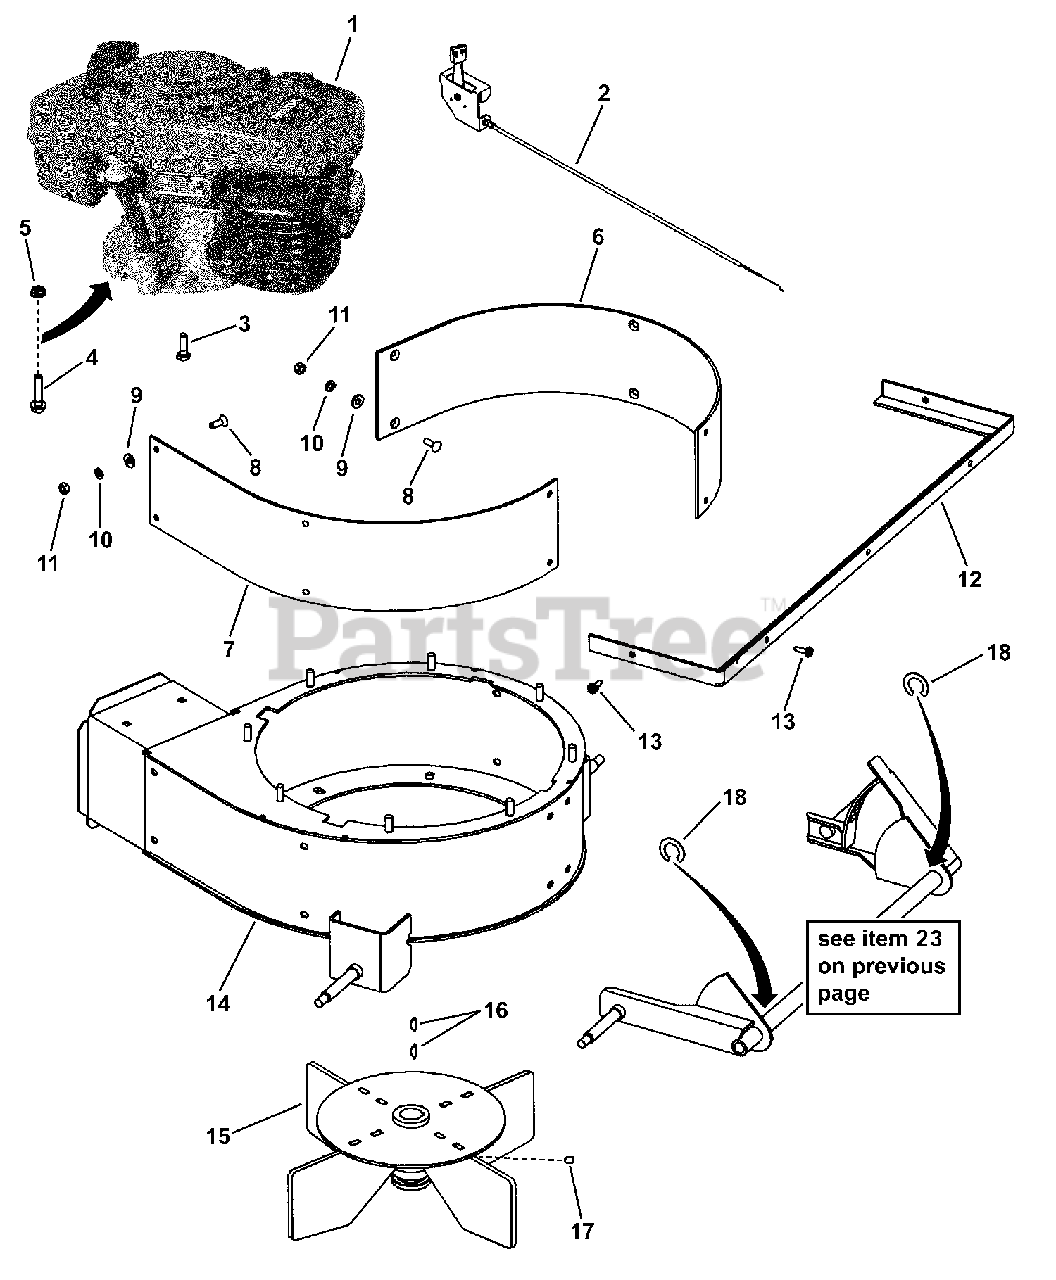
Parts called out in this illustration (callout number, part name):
1	* ENGINE, 5.5HP Honda GXV, Recoil Start, GXV160K1N1AH
2	CABLE, Throttle, Honda
3	SCREW, 5/16-24 x 1" Hex Head Cap
4	BOLT, 5/16-18 x 1-1/2" Hex Flange Lock
5	NUT, 5/16-18 Hex Flange Lock
6	LINER, Vacuum Housing L.H.
7	LINER, Vacuum Housing R.H.
8	SCREW, 1/4-20 x 3/4" Flat Head Machine
9	WASHER, .28 x .63 x .06 Flat
10	WASHER, .263 Split Lock
11	NUT, 1/4-20 Hex
12	FRAME, Inlet Protection
13	SCREW, #10 x 3/4" Hex Washer
14	WELDMENT, Upper Housing, Commercial
15	WELDMENT, Impeller, Honda Commercial
16	KEY, #55 Hi-Pro
17	SETSCREW, 1/4-20 x 3/8", Socket Head Knurled Cup Point
18	WASHER, Shim
